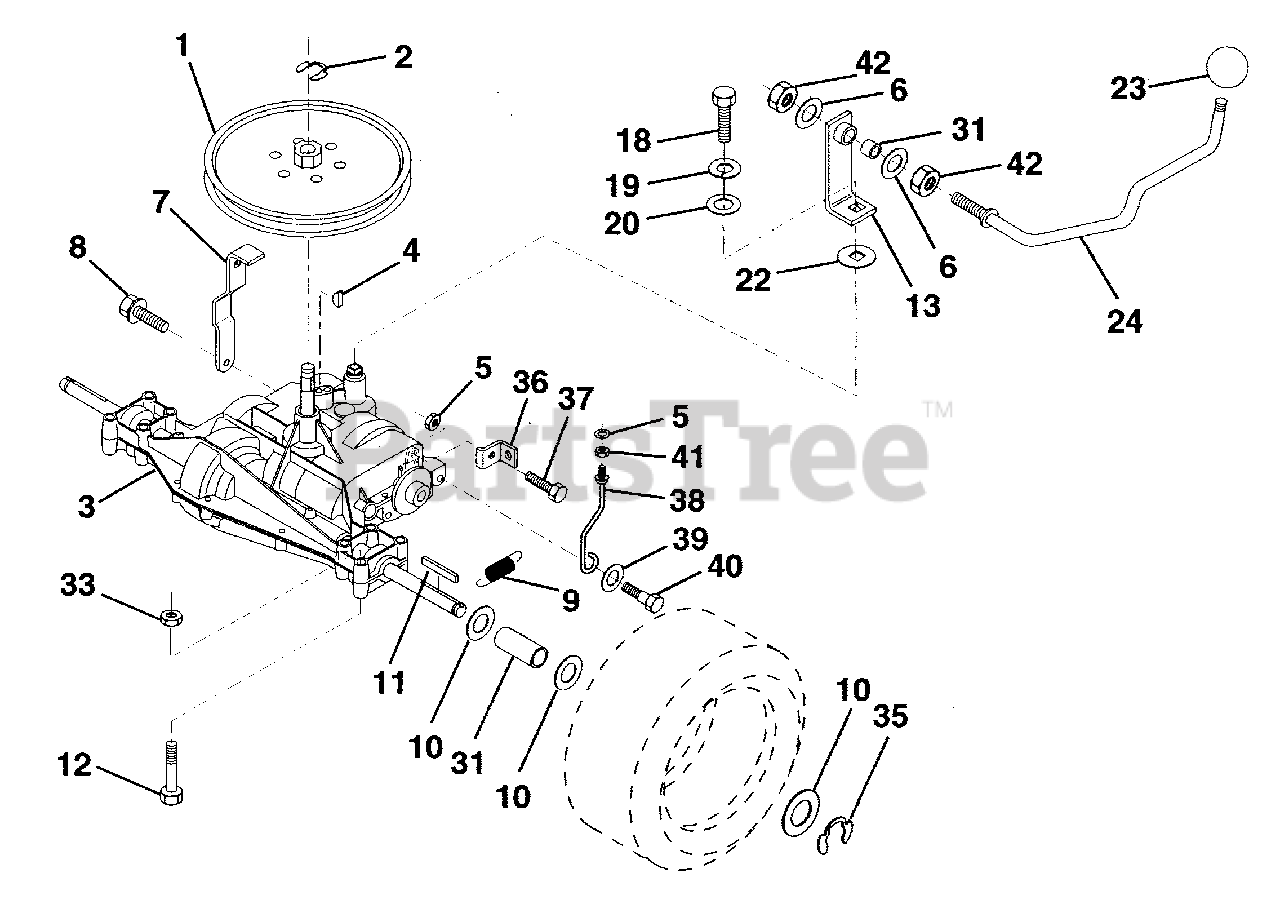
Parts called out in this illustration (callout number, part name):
2	Ring, Retainer
4	Key, Woodruff #9
5	Nut, Crownlock 5/16-18
6	Washer 15/32 x 1 x 12 Ga.
7	Strap, Torque
8	Screw, Hex Head, Thd. Roll. 5116-18 x 314
9	Spring, Brake
10	Washer 25/32 x l-1/4 x 16 Ga.
11	Key, Square
12	Bolt Fin Hex 3/8 - 16 x 2 3/4
13	Bracket Asm., Shft Cntr
18	Bolt, Hex Head, Fin. l/4-28 UNF x 3/4 Grade 8
19	Washer, Lock l/4
20	Washer 9/32 x 3/4 x 10 Gauge
22	Washer, Shift Plate
23	Knob, Shift Control
24	Rod, Shift Center
33	Nut, Crownlock 3/8 x 16 Unc
36	Bracket Brake
37	Bolt, Carriage 5/l 6-l 8 UNC x 3/4
38	Keeper Belt RH
39	Washer l/32 x 1 x 12 Ga.
40	Bolt, Shoulder 5/26 - 18
41	Nut, Crowlock 5/l 6 - 18
42	Nut, Centerlock
